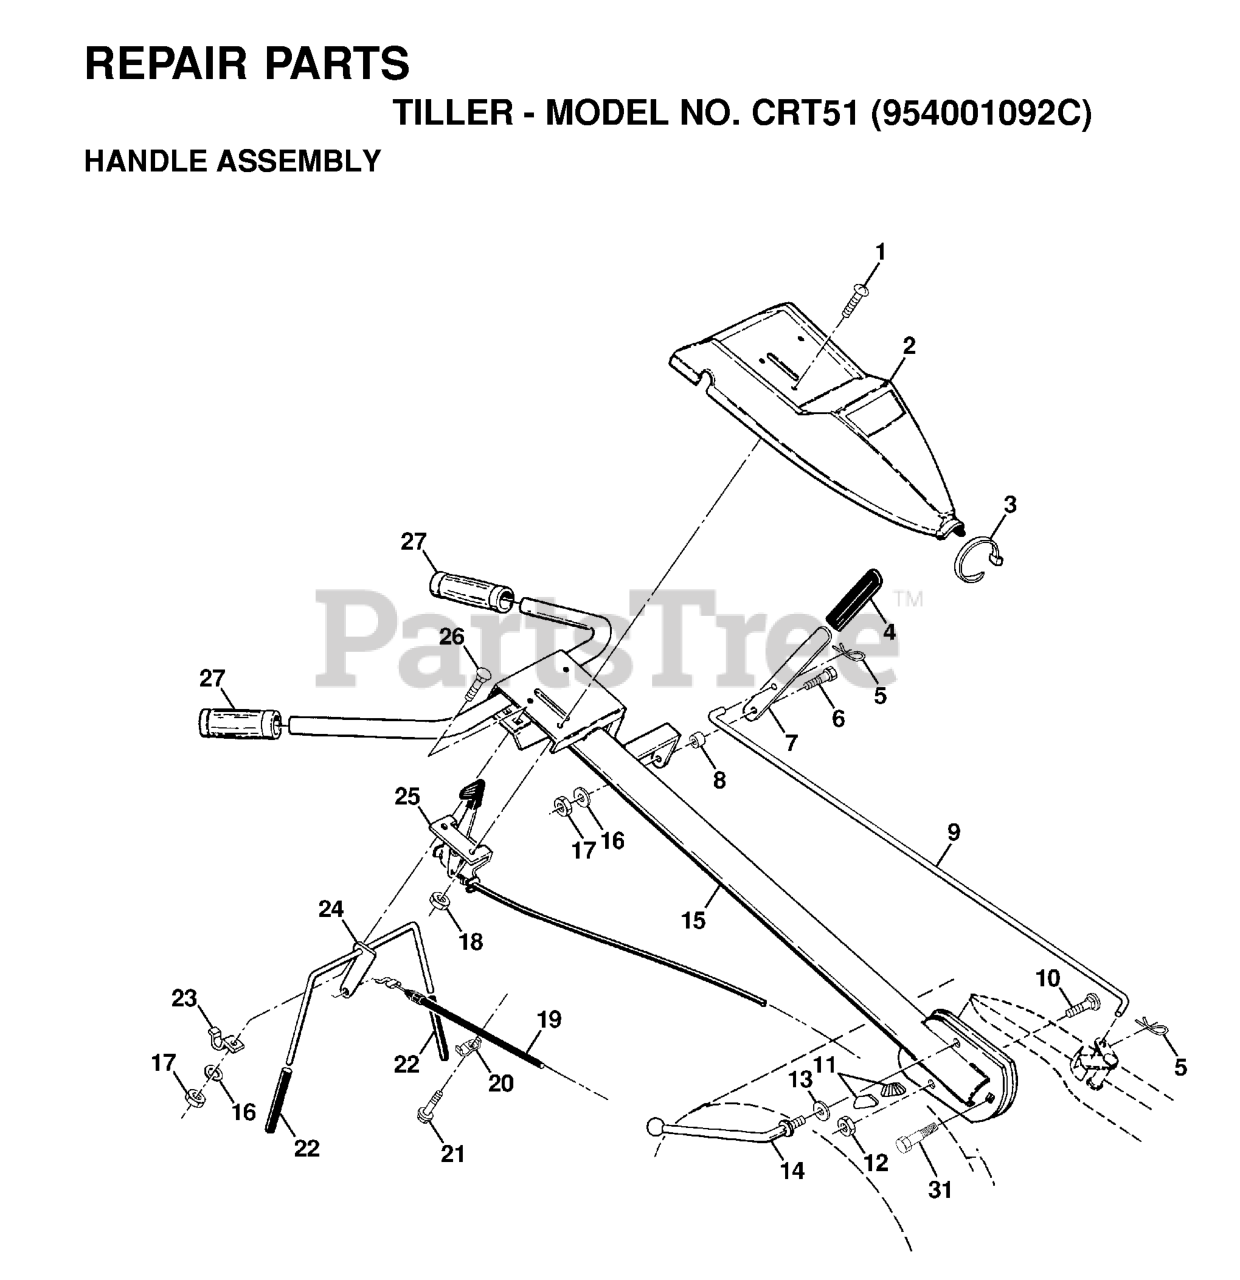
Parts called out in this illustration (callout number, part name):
1	SCREW.PNHD.10-24
3	TIE CABLE CRT
4	GRIP T
5	RETAINER M
6	SHOULDER BOLT ST
7	SHIFT HANDLE CRT
8	GROMMET.RUBBER.CRT.TILLER
9	SHIFT ROD CRT
10	BOLT D
11	LOCK.HANDLE.CRT
12	LOCKNUT
13	WASHER CRT
14	LEVER.LOCK.CRT
15	HANDLE
16	LOCKWASHER
17	NUT
18	NUT **
19	CABLE, CLUTCH 48 "Z"
20	CONDUIT.CLIP.PLATED
21	TAPPING SCREW
22	GRIP BAR CRT(1)
23	CLAMP.BAR.CRT.BLACK
24	BAR ASSY CONTROL
25	CONT,THROTTLE
27	KIT.GRIP.HANDLE.5.00.BLK.VINYL
31	BOLT.PIVOT
